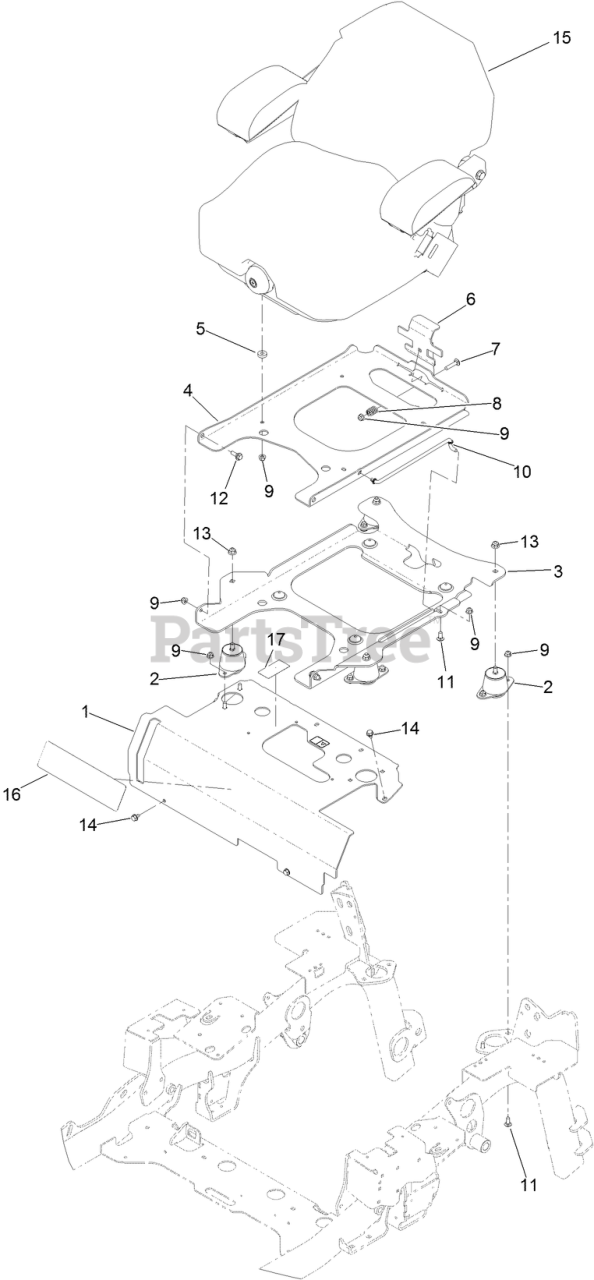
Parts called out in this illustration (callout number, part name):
1	SEAT MOUNT ASM
2	ISOLATOR-SEAT
3	PLATE-SUPPORT, TILT SEAT
4	PLATE-FRAME, SEAT
6	PLATE, SEAT LATCH
7	BOLT-CARR
8	SPRING-COMPRESSION
9	NUT-HF, NI
10	ROD-PROP
11	SCREW-CARR
12	SCREW-SHOULDER
13	NUT-HF, NI
14	SCREW
15	SEAT-SUSPENSION
16	DECAL-CONSOLE
17	DECAL-FLUID, TRANSMISSION
